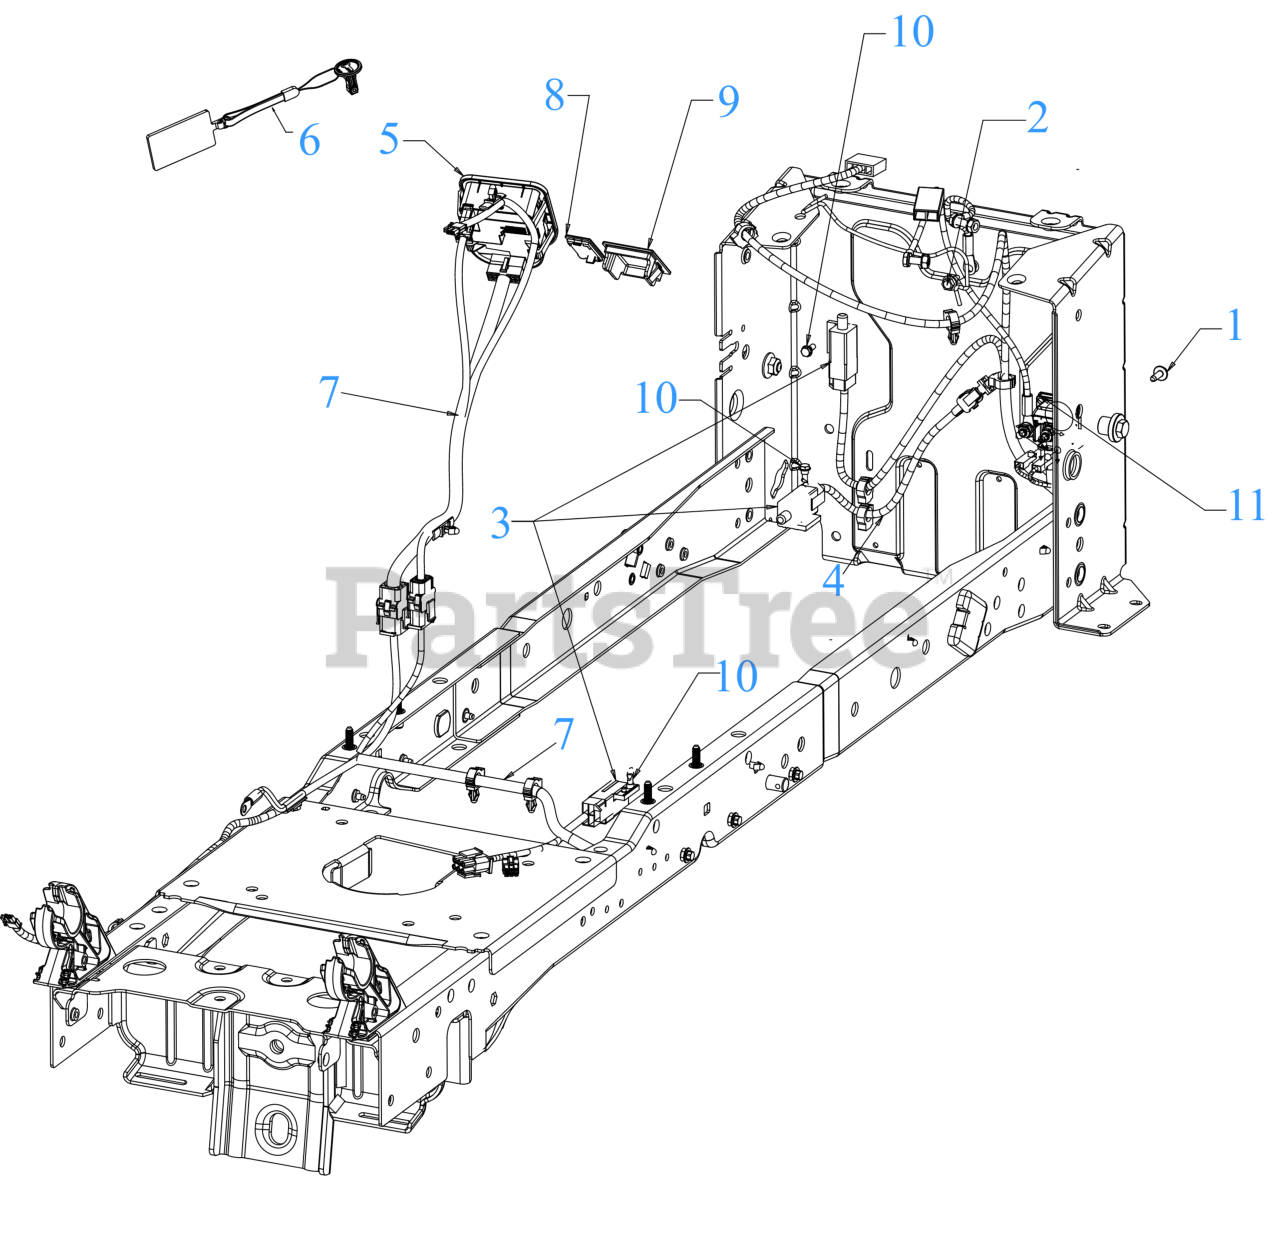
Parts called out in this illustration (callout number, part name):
1	SCREW M6-1 x .625
2	SCREW 1/4-20X.625
3	INTERLOCK SWITCH (NO/NC)
4	REVERSE HARNESS
5	MODULE (PBS/HRMTR/SVC MNDR)
6	PBS KEY
6	Cub Cadet PUSH BUTTON KEY
7	MAIN HARNESS (M-PTO/PBS/EFI)
9	DASH HOUR METER PLUG
10	SHOULDER SCREW
11	12V SOLENOID
